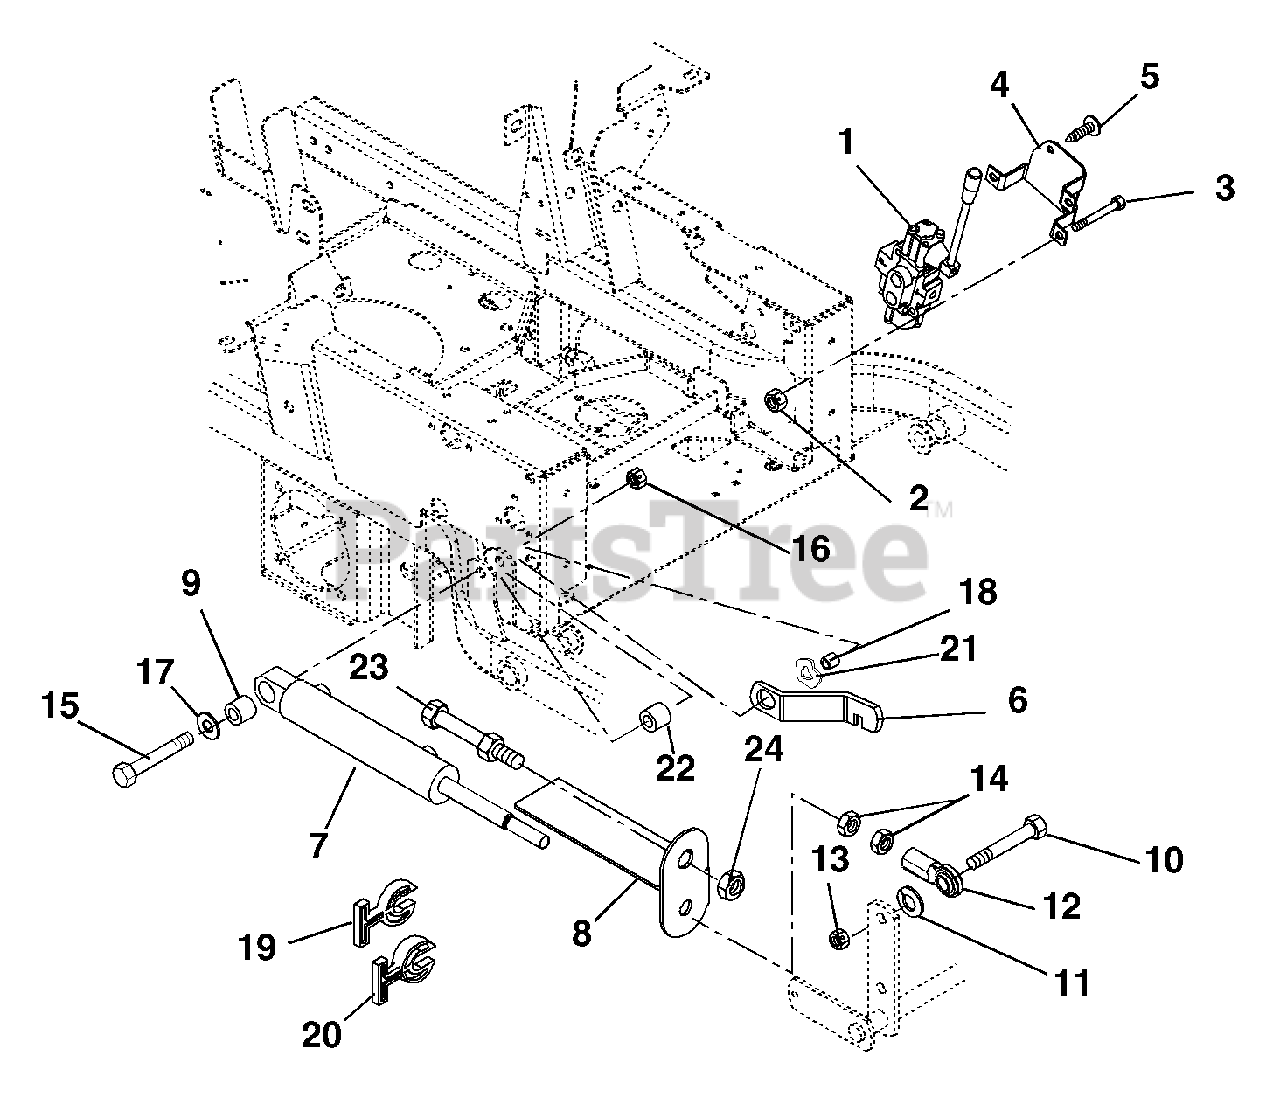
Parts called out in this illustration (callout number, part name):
1	Valve, Hydraulic
2	Nut, Locking Top Flange .31-18
3	Bolt, Hex .31-18 x 2.50 Grade 5
4	Valve Mounting Bracket
5	Screw, Tapping .38-16 x .50 Hex Washer Head
7	Cylinder, Hydraulic Lift
8	Strap, Cut Indicator/Guard
9	Bushing .516 x 1.000 x 1.050
10	Bolt, Hex .62-11 x 2.25 Grade 8
11	Washer, Lock .62 x .156
12	Rod End - Female - Right Hand .63
13	Nut, Locking Center .62-11
14	Nut, Jam .625-18
15	Bolt, Hex .50-13 x 3.50 Grade 5
16	Nut, Locking Top Flange .50-13
17	Washer, Flat Steel .515 x 1.625 x .25
18	Bushing, Flange .515 x .75 x .275 x 1.12
19	Stop, Cylinder .34 Thick
20	Stop, Cylinder .68 Thick
21	Washer, Wave .076 x 1.12 xz .08
22	Spacer .50 I.D. x .88 O.D. x .88
24	Nut, Jam Center Lock .75-16
